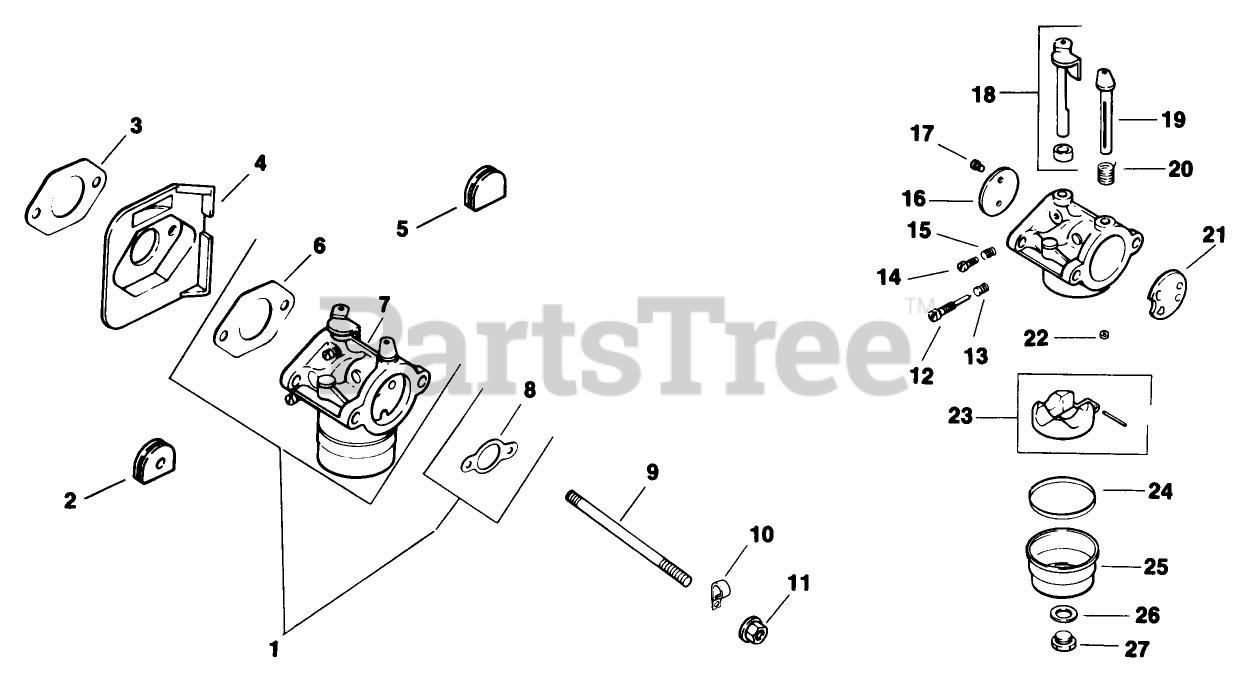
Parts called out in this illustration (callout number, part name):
1	Kit-Carburetor
2	Grommet (Only On: 72042, 72063, 72062, 72043)
3	Gasket-Carburetor (Only On: 72042, 72063, 72062, 72043)
4	Deflector-Heat (Only On: 72042,72043,72062,72063)
5	Grommet
6	Gasket-Carburetor (Only On: 72042, 72063, 72062, 72043)
7	Carburetor (Ref.)
8	Gasket-Air Cleaner (Only On: 72042, 72043, 72062, 72063)
9	Stud M6x1.0x110 (Only On: 72042,72043,72062,72063)
10	Clip-Cable (Only On: 72103)
12	Needle-Idle Fuel Adjust (Only On: 72042, 72063, 72062, 72043)
13	Spring-Idle Fuel (Only On: 72042, 72063, 72062, 72043)
14	Screw-Idle Speed Adjust (Only On: 72042,72043,72062,72063)
15	Spring-Idle Fuel (Only On: 72042, 72063, 72062, 72043)
16	Plate-Throttle (Only On: 72042,72043,72062,72063)
17	Screw-Throttle Plate (Only On: 72042,72043,72062,72063)
18	Shaft-W/Lever Seal (Only On: 72042, 72063, 72062, 72043)
19	Shaft-Choke (Only On: 72042. 72063, 72062, 72043)
20	Spring-Choke Return (Only On: 72042,72063, 72062, 72043)
21	Plate-Choke (Only On: 72042, 72063, 72062, 72043)
22	Jet-Main
23	Kit-Float (Only On: 72042,72043,72062,72063)
24	Gasket-Bowl (Only On: 72042,72043,72062,72063)
25	Bowl-Fuel (Only On: 72042, 72063, 72062, 72043)
26	Gasket-Bowl Screw (Only On: 72042, 72063, 72062, 72043)
27	Screw-Fuel Bowl (Only On: 72042, 72063,72062, 72043)
